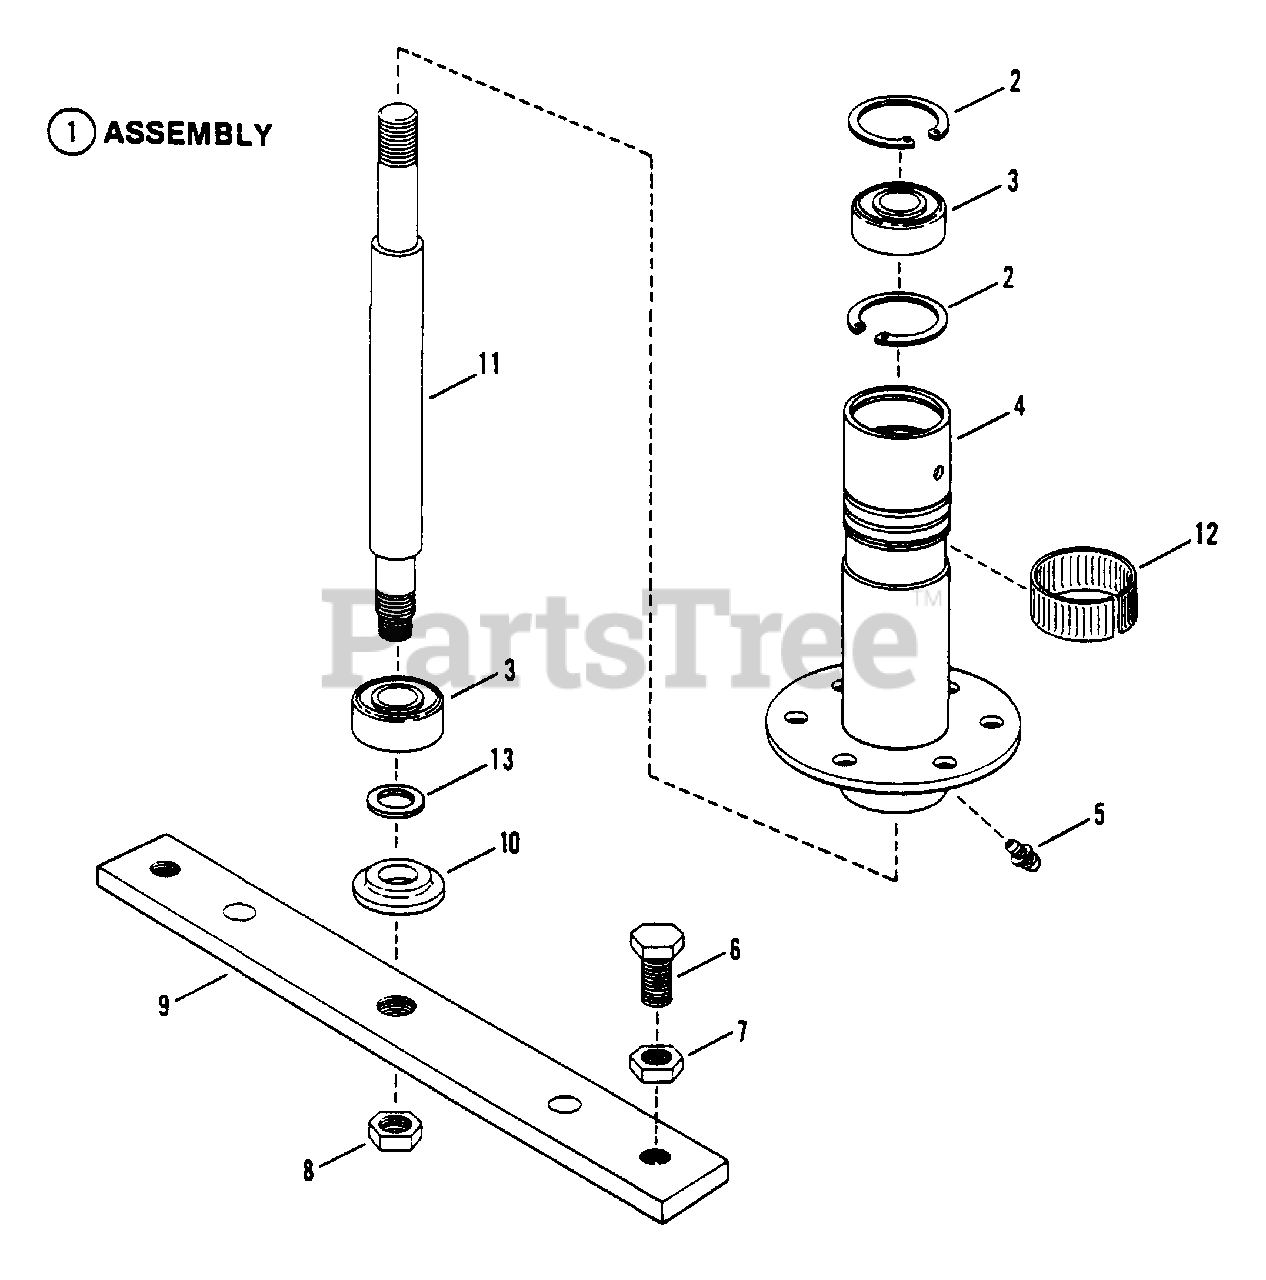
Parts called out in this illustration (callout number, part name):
1	ASSEMBLY, Spindle Housing
2	RING, Retaining
3	BEARING, Spindle
4	HOUSING, Spindle
5	FITTING, Lube (Press fit for .187 hole-no ball)
6	SCREW, 1/2-20 x 1" Hex Head Cap (GR. 5)
7	NUT, 1/2-20 Hex Jam
8	NUT, 5/8-18 Hex Lock
9	HOLDER, Blade
10	WASHER, Spindle
11	SPINDLE, Shaft (10.237" Long)
12	RING, Tolerance
13	WASHER, 3/4 Shim
14	WASHER, Centering
